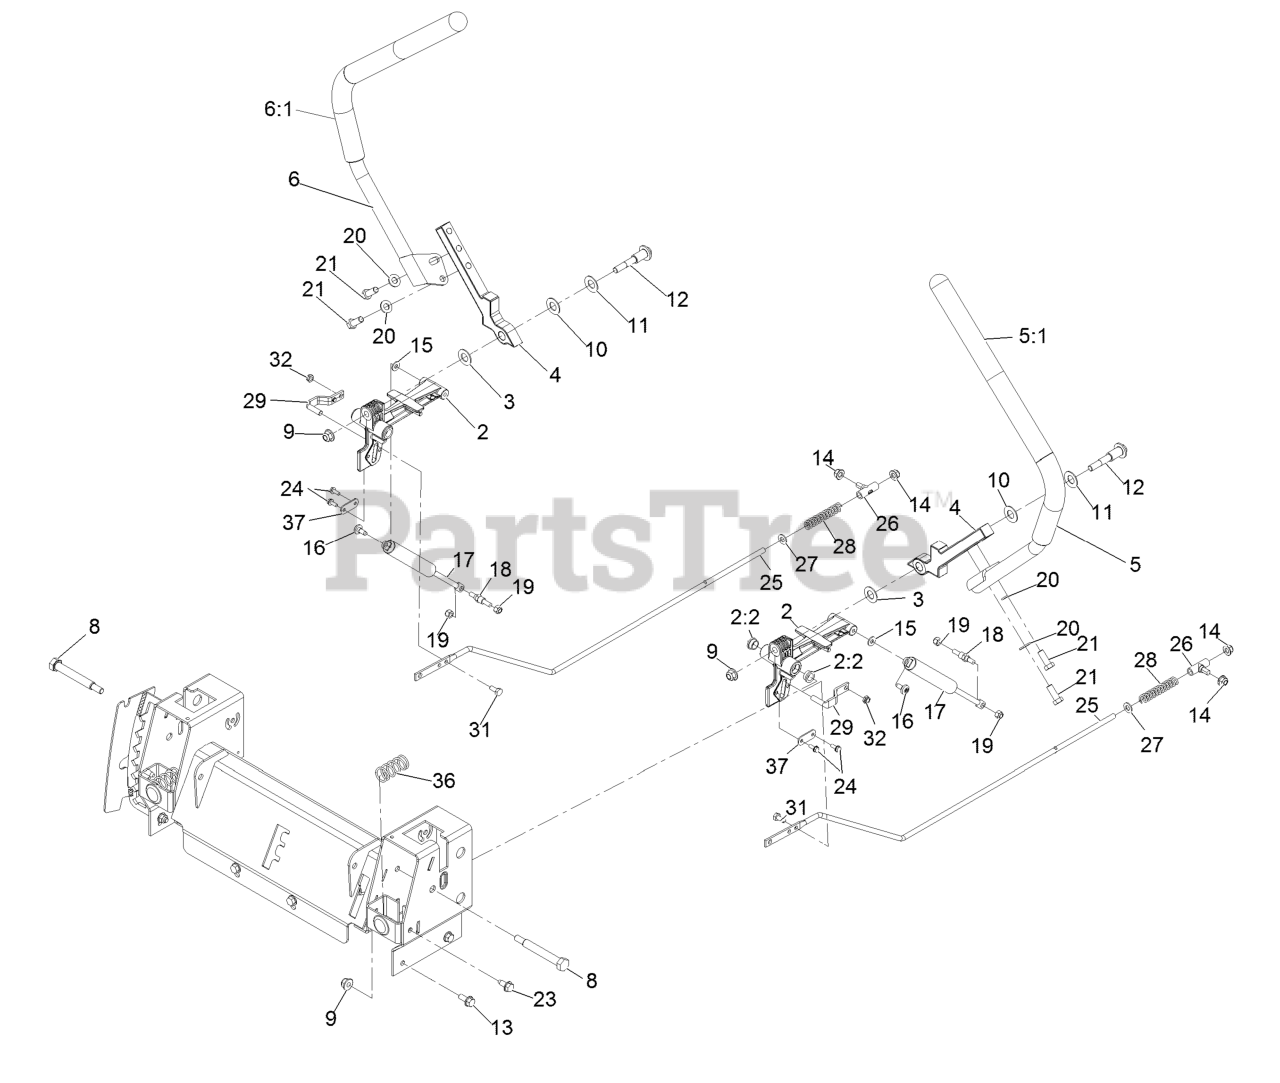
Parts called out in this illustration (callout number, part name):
2	Actuator Arm ASM
2:2	Bushing-Flange
3	Washer-Nylon
4	Arm-Control
5	Handle-Control, LH
6	Handle-Control, RH
8	Bolt-Pivot
9	Nut-Nyloc 3/8-16 Flg
11	Washer-Belleville
12	Bolt-Pivot
13	Screw-HH Flg 5/16-18 X 3/4
14	Nut-Nyloc 5/16-18 Flg
16	Screw-1/4-20 X 1/2 Tf Torx Plus
18	Stud-Damper
19	Nut-Nyloc 1/4-20
20	Washer-3/8 SAE
21	Screw-HH 3/8-16 X 1
23	Screw-HWH 5/16-18 X 3/4 Tf
24	Screw-HWH #10-24 X 1/2 Taptite
25	Rod-Hydro
26	Mount-Rod, Hydro
27	Washer-5/16 SAE
29	Pin-Rod, Hydro
31	Screw-HH 1/4-20 X 5/8
32	Nut-Nyloc 1/4-20 Thin
36	Spring-Return
37	Plate-Stop, Hydro
